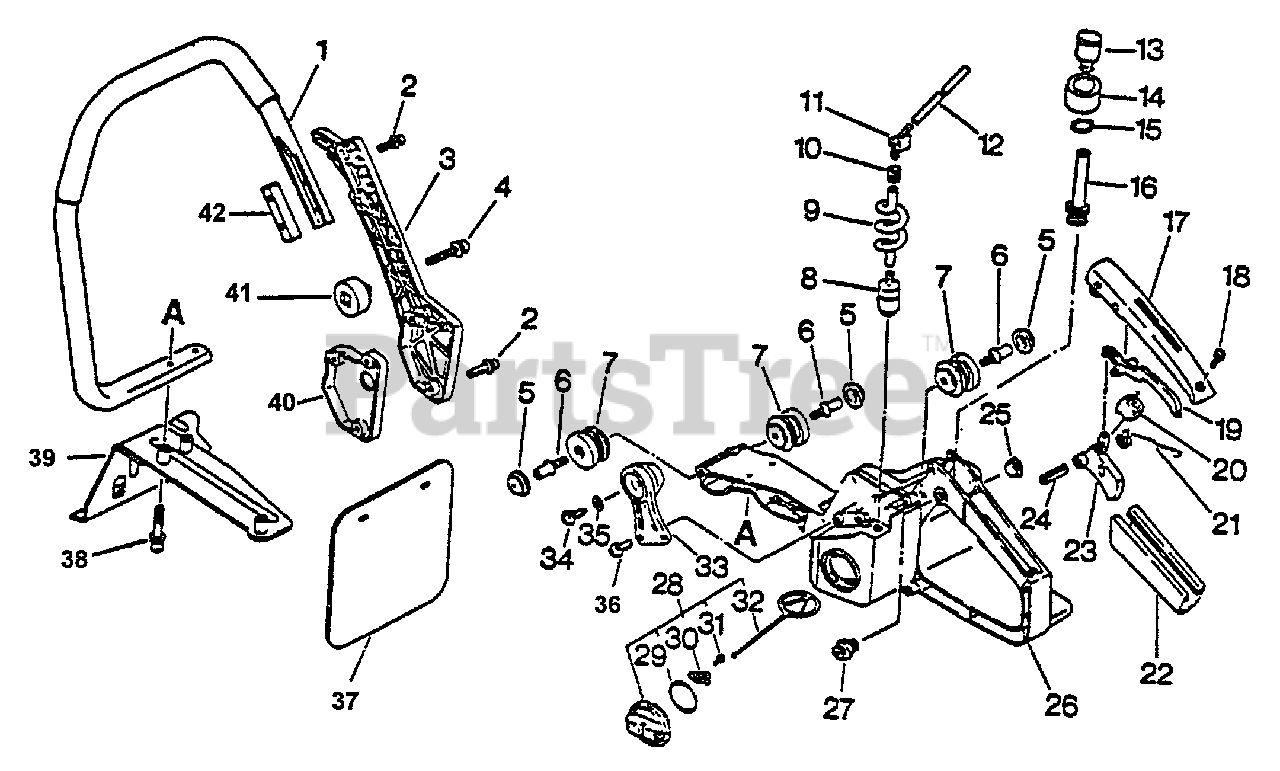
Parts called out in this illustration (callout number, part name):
1	HANDLE, FRONT
2	SCREW 5×35
3	SUPPORTER, FRONT HNDL. KIT
4	SCREW 5×30
5	CAP, CUSHION
8	FILTER, FUEL
9	PIPE, FUEL
10	GROMMET
11	CONNECTOR, PIPE
13	VENT ASSY
14	HOLDER, VENT
16	PIPE, VENT
17	COVER, HANDLE
18	SCREW 4×14
19	LEVER, THROTTLE LOCKOUT
20	CUSHION, THROTTLE
21	SPRING, THROTTLE RETURN
22	GRIP, HANDLE
23	TRIGGER, THROTTLE
24	PIN, SPRING Ø5×25 MM
26	HANDLE - REAR
27	LOCK, THROTTLE TRIGGER
28	CAP ASSY, FUEL
29	O-RING 29
30	RETAINER, CONNECTOR
31	SCREW, TAPPING 3×8
32	CONNECTOR, CAP L= 60 MM
34	SCREW 5×14
35	WASHER, FLAT 5.5×10×0.8
36	SCREW 5×14
37	SHIELD
38	BOLT 5×30
39	FIXTURE, HANDLE
40	SPACER
